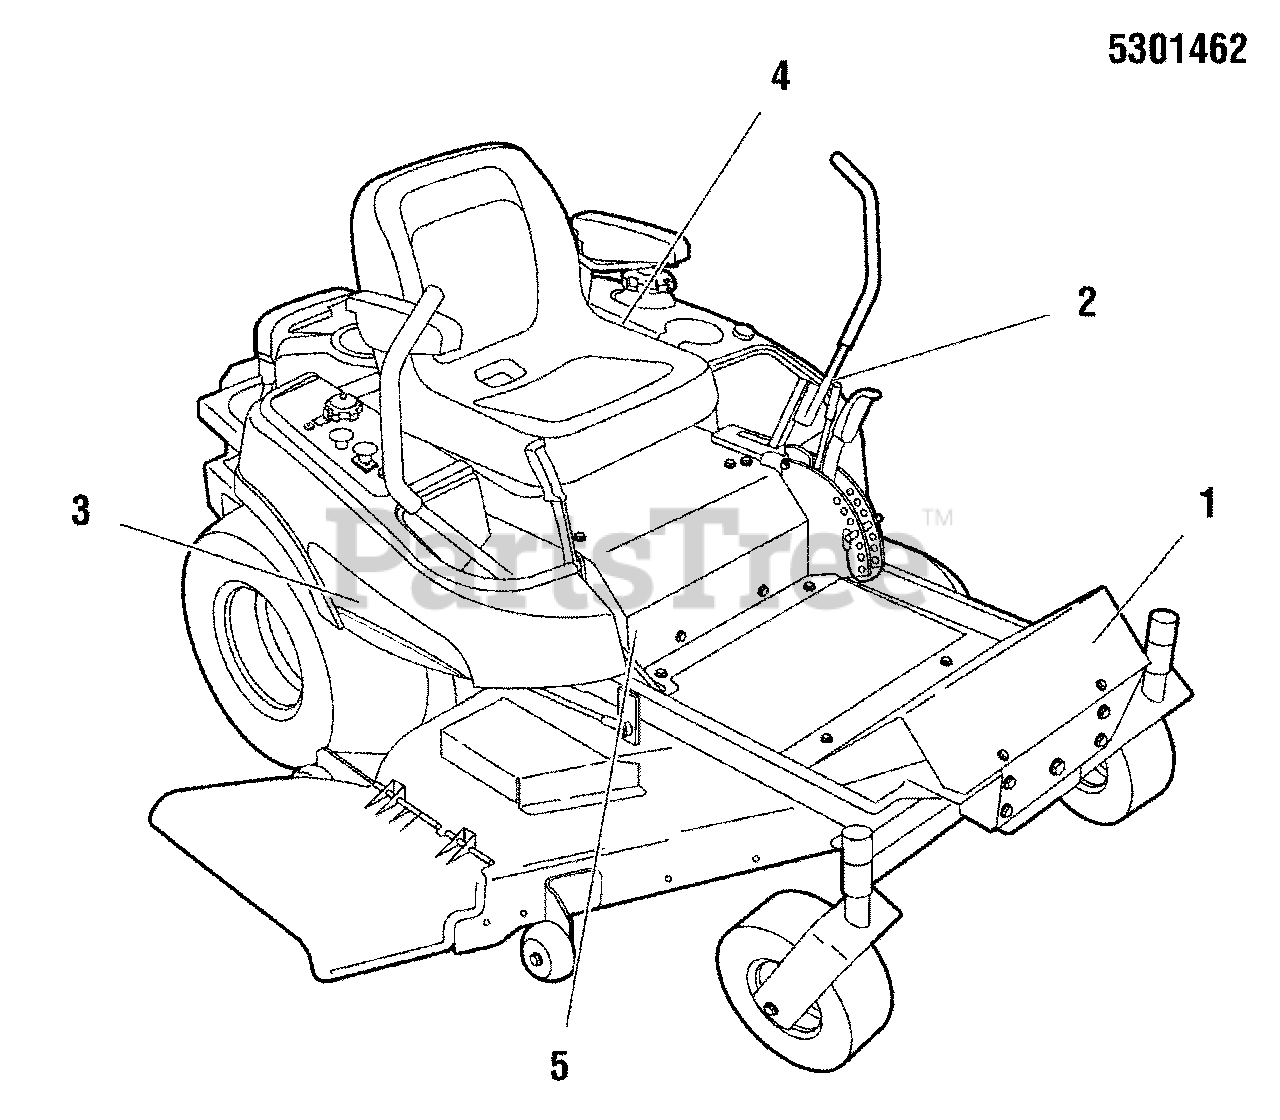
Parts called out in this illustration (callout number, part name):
1	DECAL, SNAPPER, FRONT
2	DECAL, LOGO, STRIPE - LH
3	DECAL, LOGO, STRIPE - RH
4	DECAL, TOUCH UP PAINT SNAPPER/MASSEY
5	DECAL, 355Z 26HP MODEL
